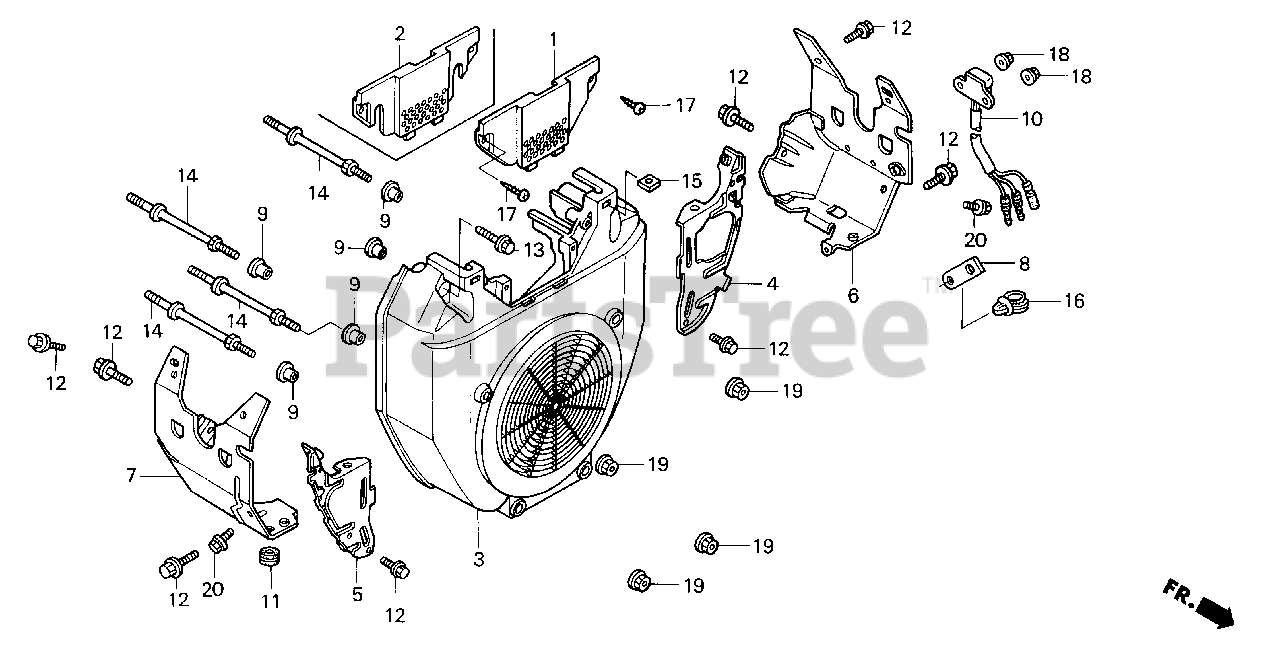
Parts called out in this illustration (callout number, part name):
1	COVER, FUEL PUMP
3	COVER, FAN *R8* (BRIGHT RED)
4	PLATE, R. SIDE
5	PLATE, L. SIDE
6	SHROUD, R. (OIL ALERT)
7	SHROUD, L.
9	COLLAR B, TAILLIGHT
10	ALERT UNIT ASSY., OIL
11	RUBBER, RR. FENDER CUSHION
12	BOLT, FLANGE (6X12) (CT200)
13	BOLT, FLANGE (6X23)
14	BOLT, STUD (6X71)
15	NUT, SQUARE (5MM)
17	SCREW, TAPPING (5X20)
18	NUT, FLANGE (5MM)
19	NUT, FLANGE (6MM)
20	BOLT, FLANGE (6X8)
